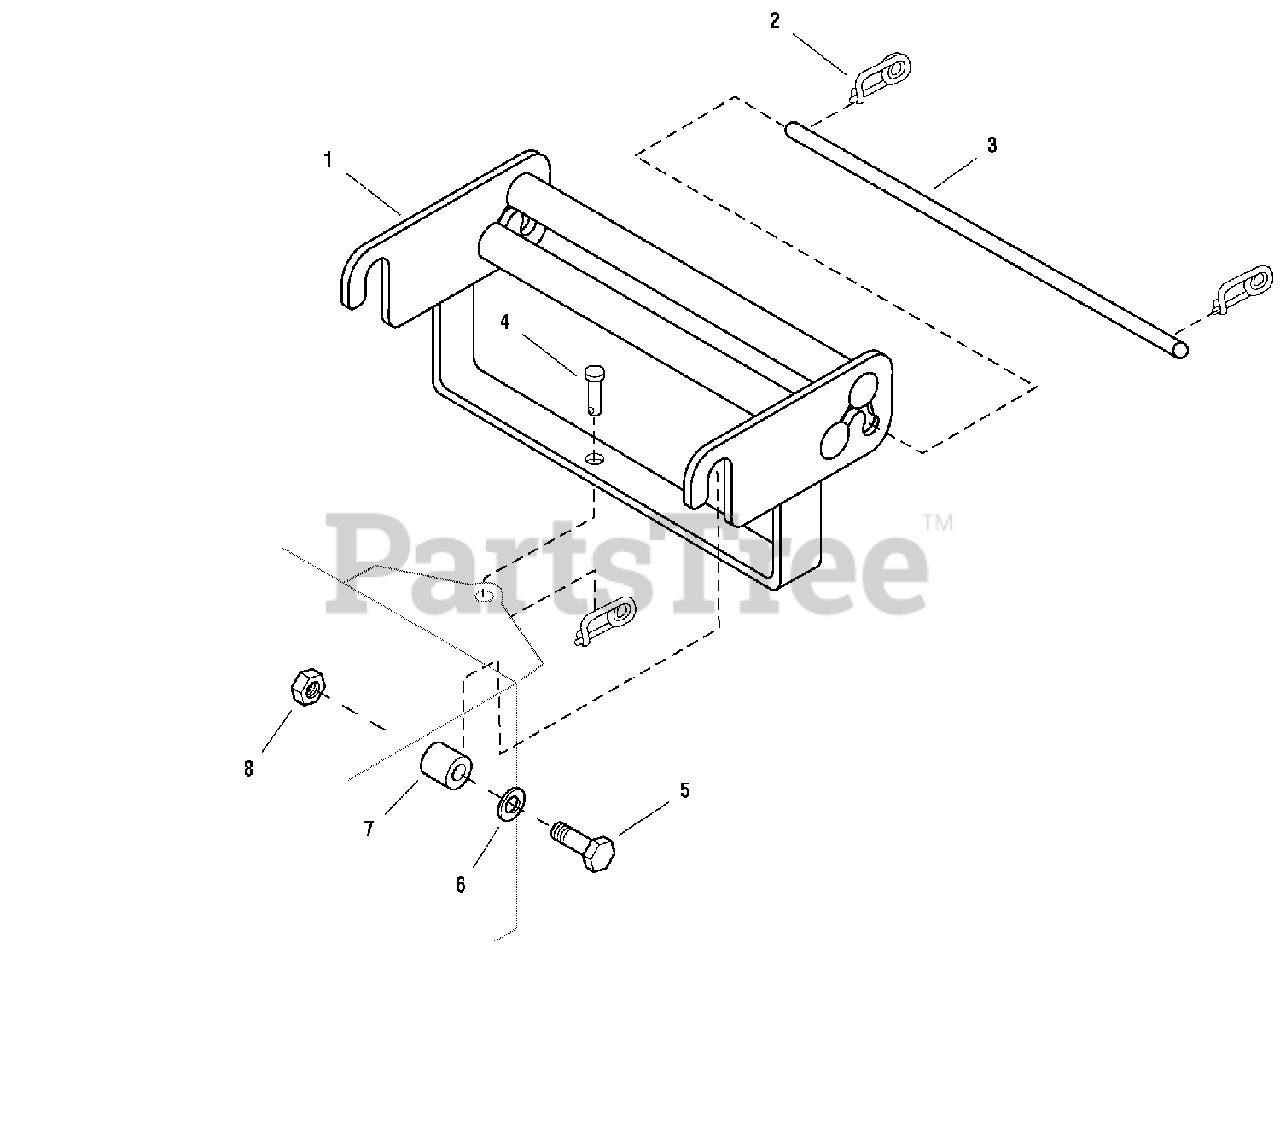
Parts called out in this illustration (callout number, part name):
1	HITCH ASSEMBLY
2	CLIP, Safety
3	ROD, Locking
5	CAPSCREW, 3/8-16 x 1-1/4
6	WASHER
8	NUT, Hex Flange Whiz Lock, 3/8-16
